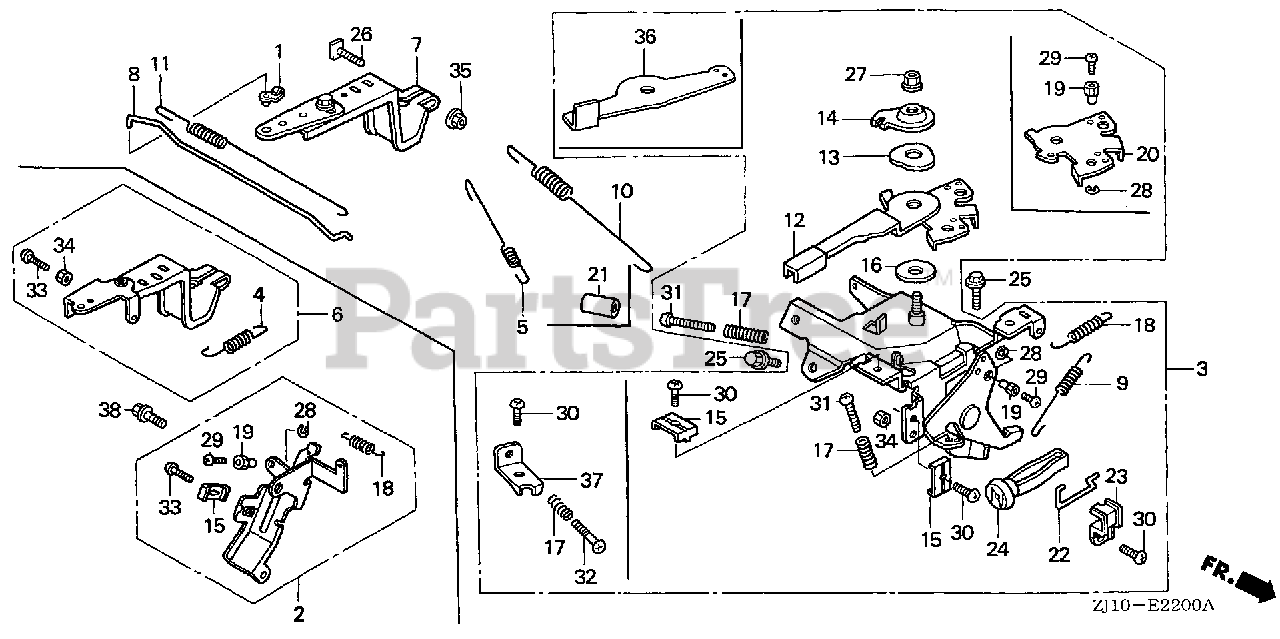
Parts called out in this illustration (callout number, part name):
1	JOINT, ROD
3	CONTROL ASSY.
5	SPRING, STARTER
7	ARM, GOVERNOR
8	ROD, GOVERNOR
9	SPRING, GOVERNOR
10	SPRING, GOVERNOR
11	SPRING, THROTTLE RETURN
12	LEVER, CONTROL
13	SPRING, LEVER
14	WASHER, CONTROL LEVER
16	SPACER, CONTROL LEVER
17	SPRING, CONTROL ADJUSTING
22	ROD, CHOKE KNOB
23	HOLDER, CHOKE KNOB
24	KNOB, CHOKE
25	BOLT, FLANGE (6X12) (CT200)
26	BOLT, GOVERNOR ARM
27	NUT, SELF-LOCK (6MM)
30	SCREW, PAN (5X12)
31	SCREW, PAN (5X25)
34	NUT, HEX. (5MM)
35	NUT, FLANGE (6MM)
